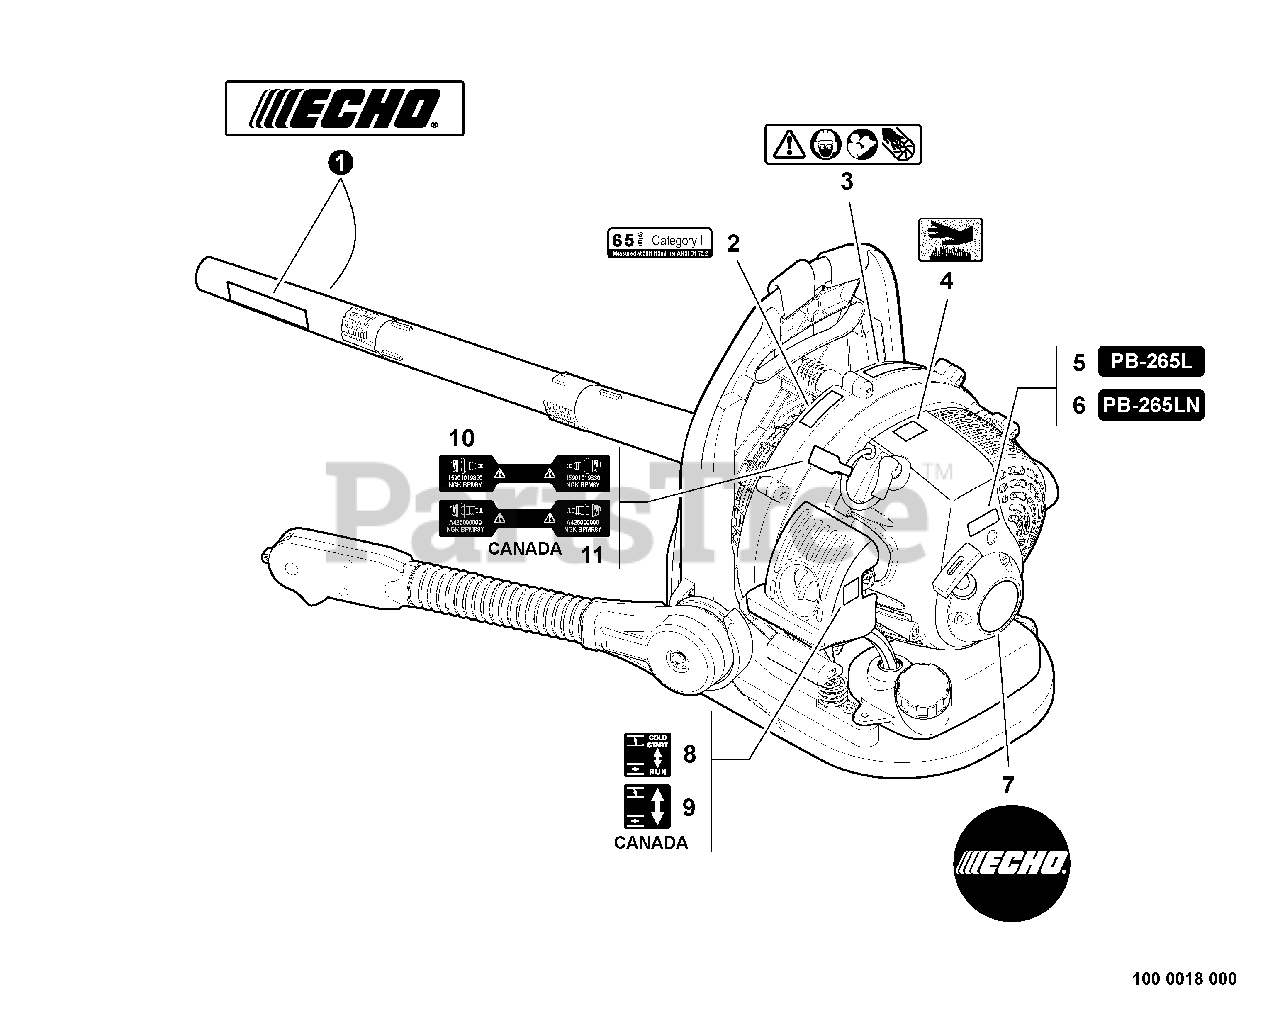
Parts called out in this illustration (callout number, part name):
1	LABEL, ECHO BLOWER TUBE
2	LABEL, NOISE
3	LABEL, CAUTION - ISO
4	LABEL, CAUTION - HOT
5	LABEL, MODEL
6	LABEL - MODEL PB-265LN
7	LABEL, RECOIL STARTER
8	LABEL, CHOKE
9	LABEL, CHOKE
10	LABEL, SPARK PLUG - BPM8Y
11	LABEL, SPARK PLUG - BPMR8Y
